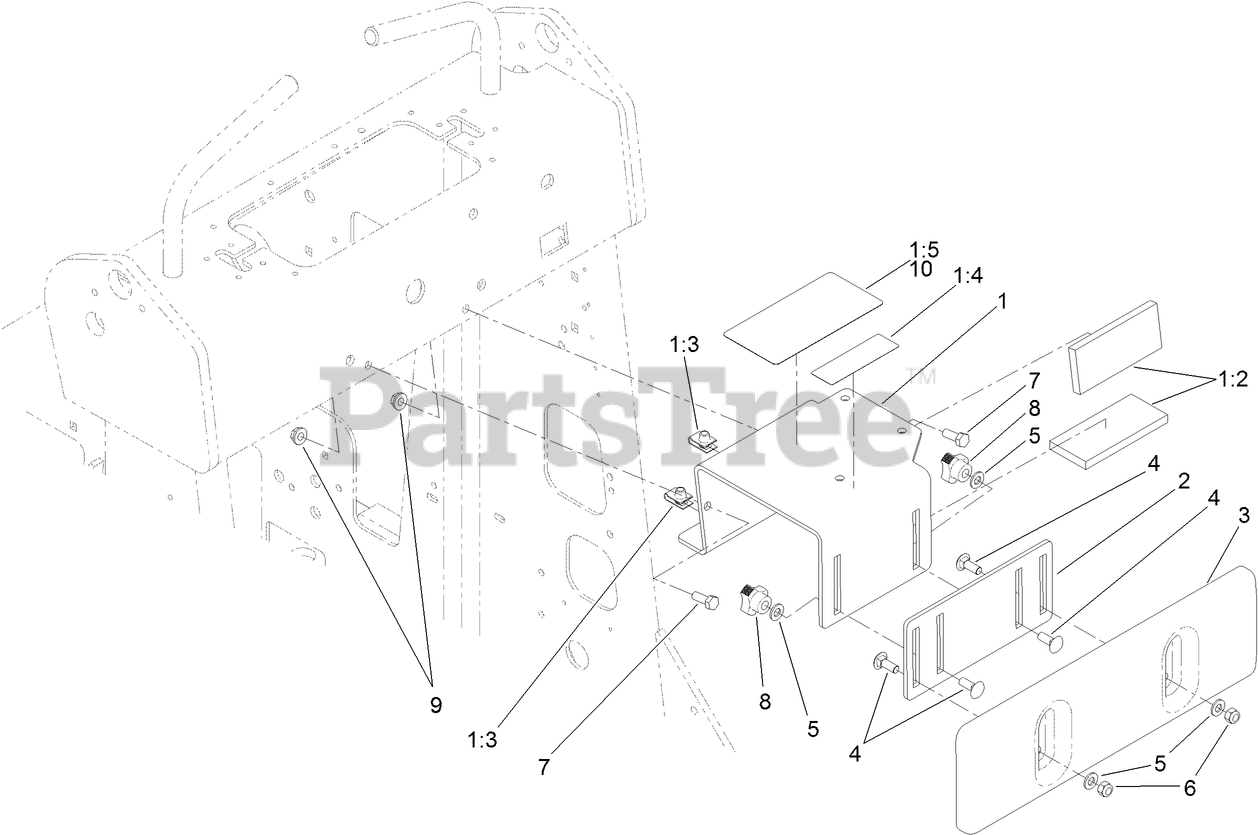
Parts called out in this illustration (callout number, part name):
1	THIGH SUPPORT BRACKET ASM
1:2	PAD-FOAM
1:3	NUT-CLIP, U
1:4	DECAL-MANUAL
1:5	DECAL-SERVICE
2	PLATE-ADJUSTING
3	SUPPORT-THIGH
4	SCREW-CARR
5	WASHER-FLAT
6	NUT-LOCK, NI
7	SCREW-HH
8	KNOB-ADJUSTMENT
9	NUT-HF
10	DECAL- SERVICE FRENCH
10	DECAL-SERVICE, GERMAN
10	DECAL-SERVICE, SPANISH
10	DECAL-SERVICE, ITALIAN
10	DECAL-SERVICE, DUTCH
10	DECAL-SERVICE, POLISH
10	DECAL-SERVICE, RUSSIAN
10	DECAL-SERVICE, SLOVAKIAN
